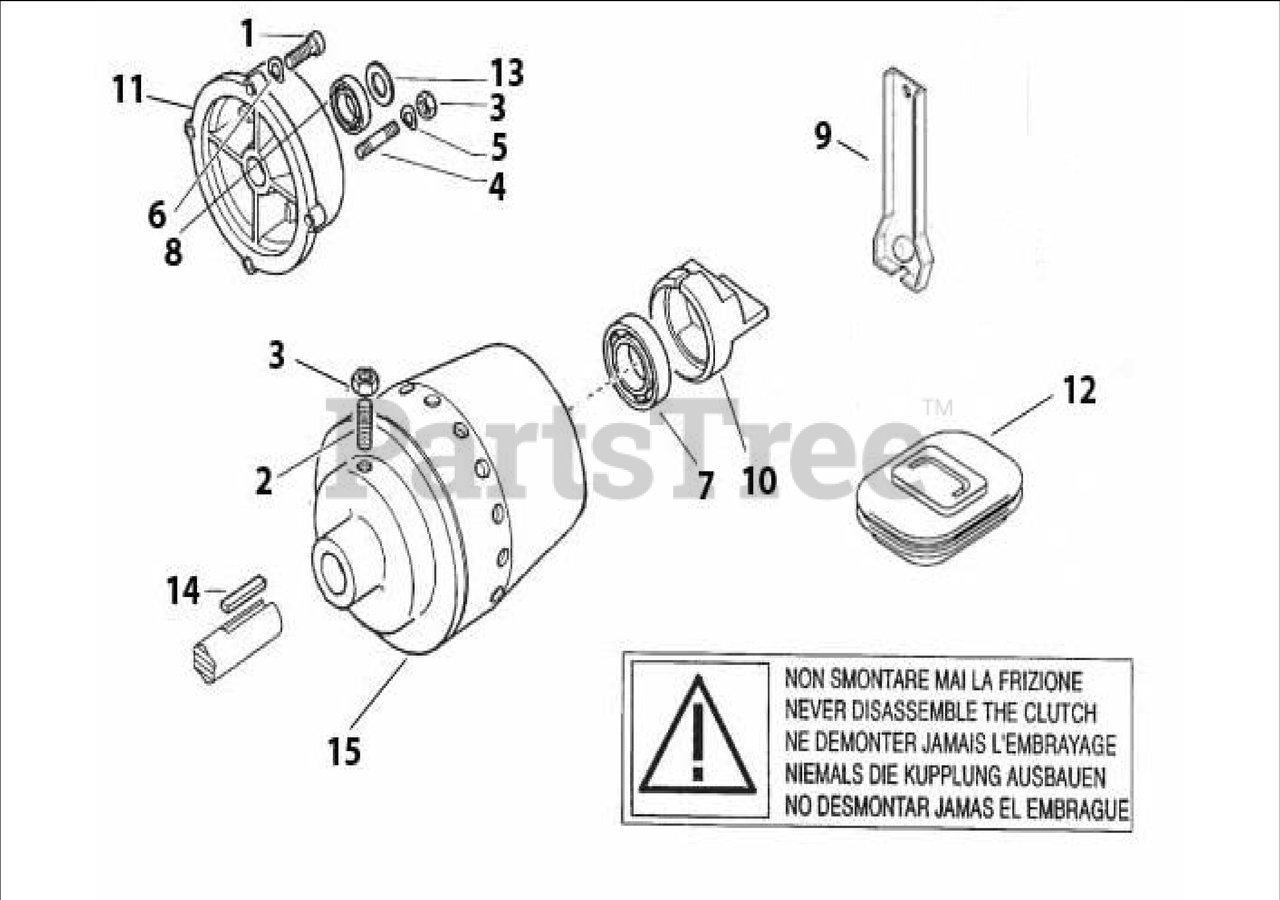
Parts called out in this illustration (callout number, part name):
1	CAPSCREW, 3/8
2	CAPSCREW, M8X30
3	NUT, M8
4	STUD, M8X40X14X4
5	WASHER, LOCK, M8.4
6	WASHER, WAVEY M10.4
7	BEARING 6203 2RS 17X40X12
8	BEARING 6006 2RS 30X55X13
9	CLUTCH LEVER
10	CONE PUSHER
11	FLANGE, ENGINE
12	BOOT/BELLOWS
13	WASHER
15	CONE CLUTCH (INCLUDES # 2,3,7,10 & 15)
